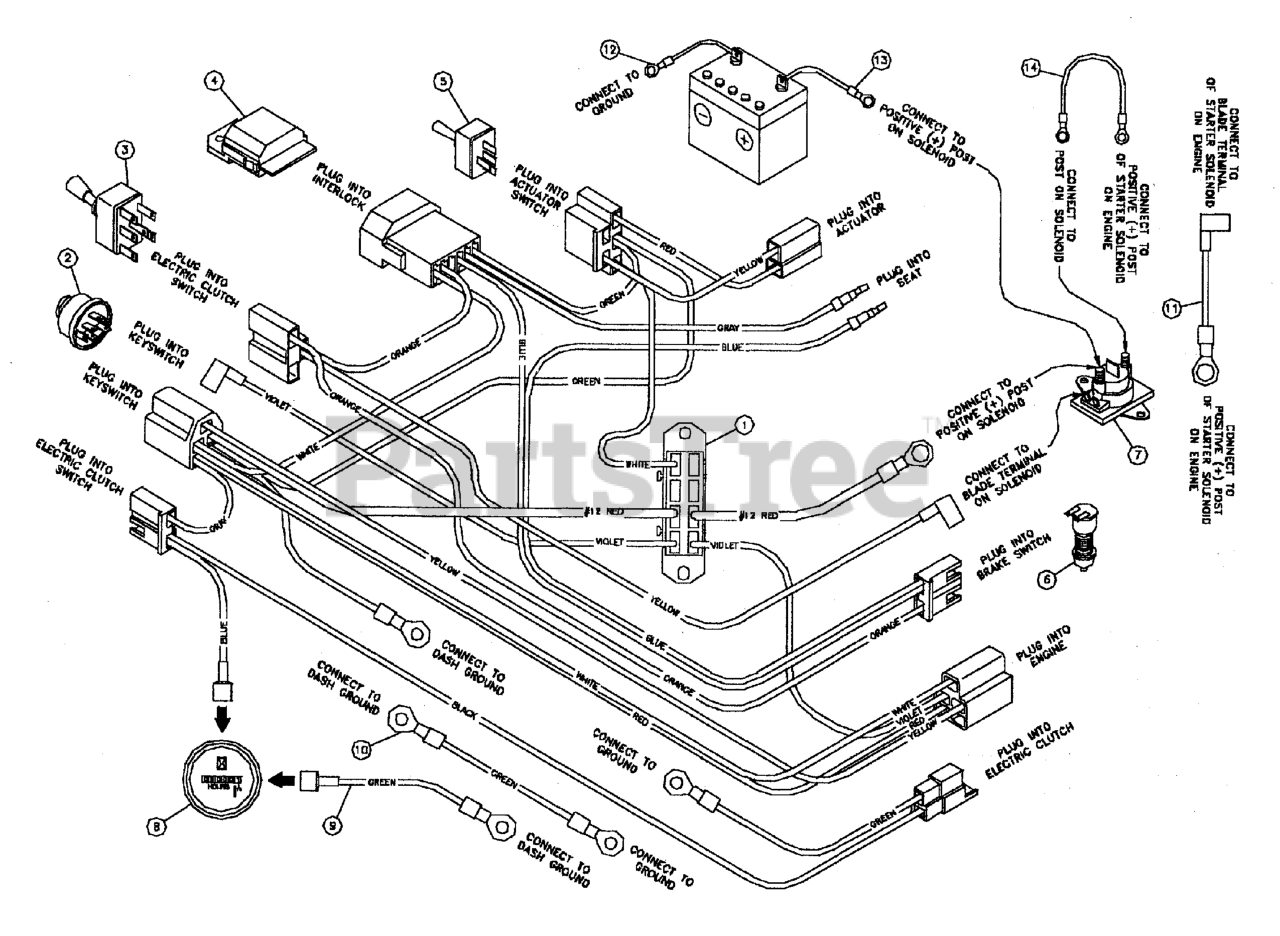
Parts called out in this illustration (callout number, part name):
1	RIDER WIRE HARNESS
2	SWITCH, IGNITION, 6 POST
3	SWITCH, Electric Clutch
4	INTERLOCK RELAY HARNESS
5	SWITCH, Actuator
6	SWITCH, Plunger, NO
7	SOLENOID, Starter
8	HOUR METER
9	HOUR METER GROUND WIRE
10	DASH GROUND WIRE
11	STARTER JUMPER WIRE
12	BATTERY CABLE, NEG, 22, 1/4-5/16
13	POSITIVE (+) BATTERY CABLE, 30"
14	STARTER CABLE
